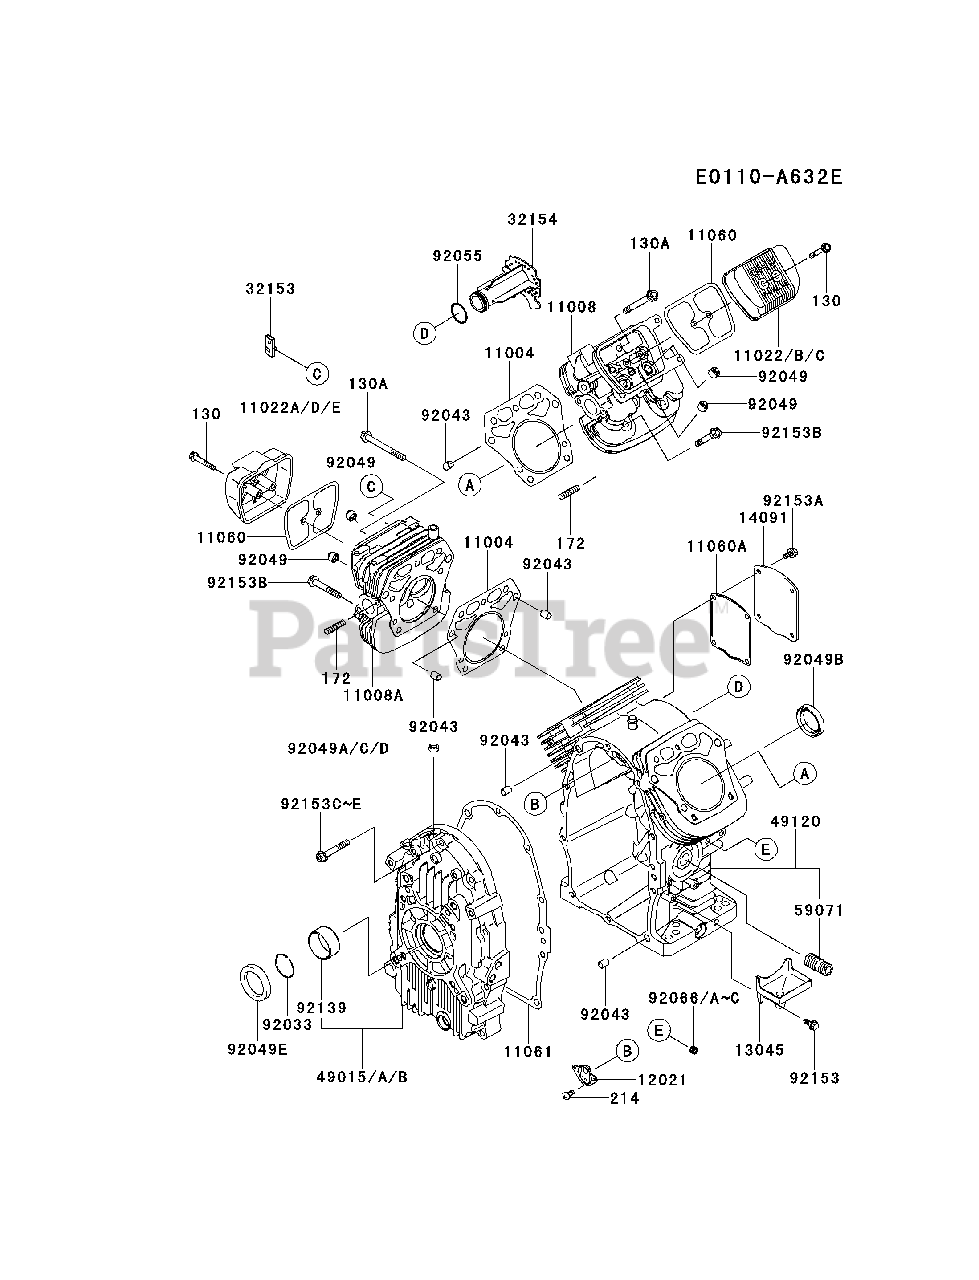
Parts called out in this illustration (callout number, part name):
130	BOLT-FLANGED,6X40
130A	BOLT-FLANGED,8X75
172	BOLT-STUD,8X18
214	SCREW-PAN+-,4X8
